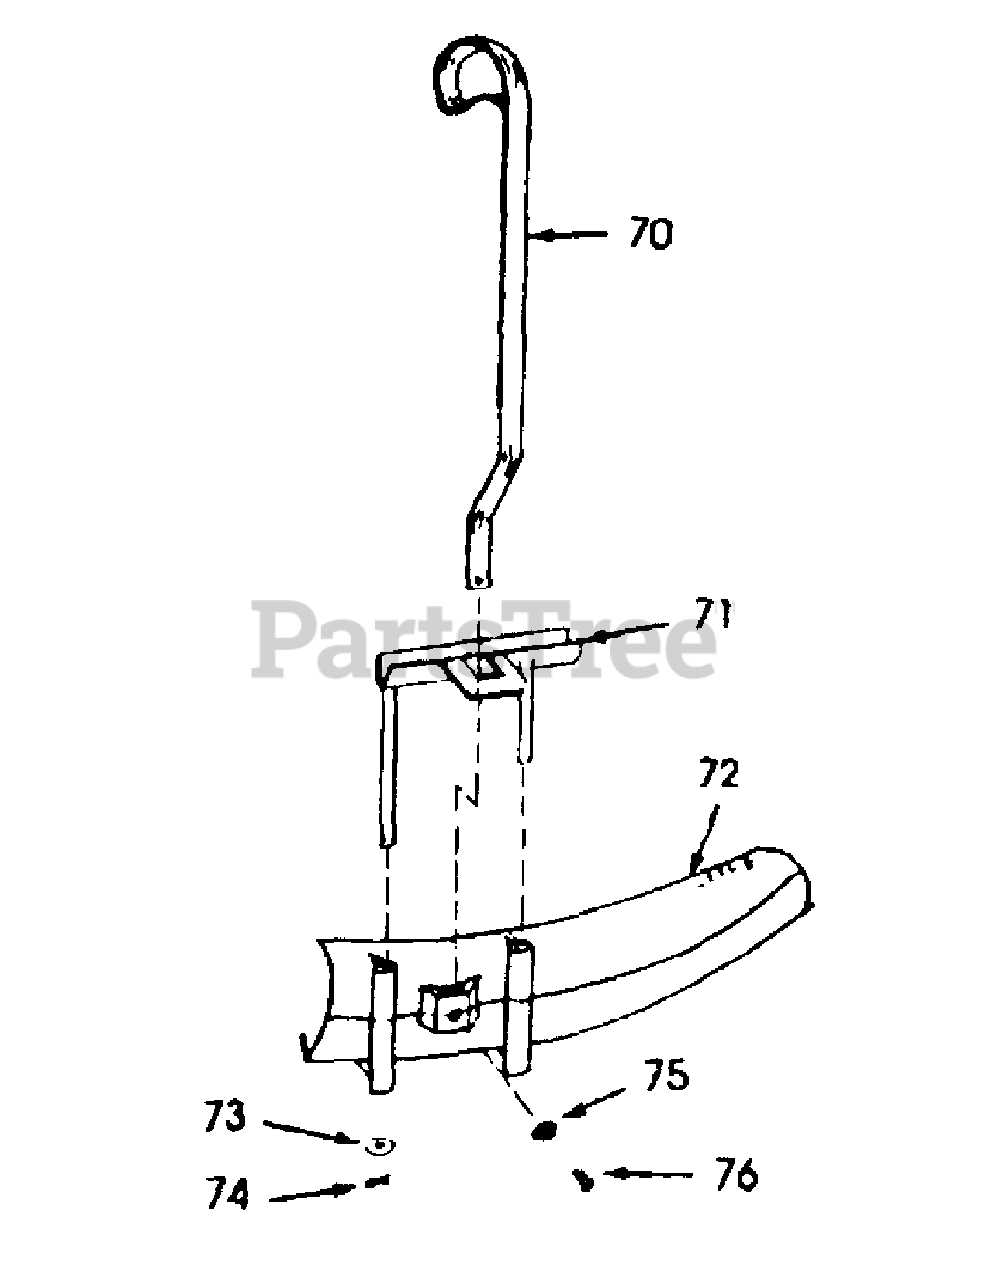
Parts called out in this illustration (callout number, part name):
70	SS Handle
71	SS Bracket
72	Deflector
73	SS Washer
74	SS Cotter Pin
75	SS Ext. Tooth Washer
76	SS Machine Screw
